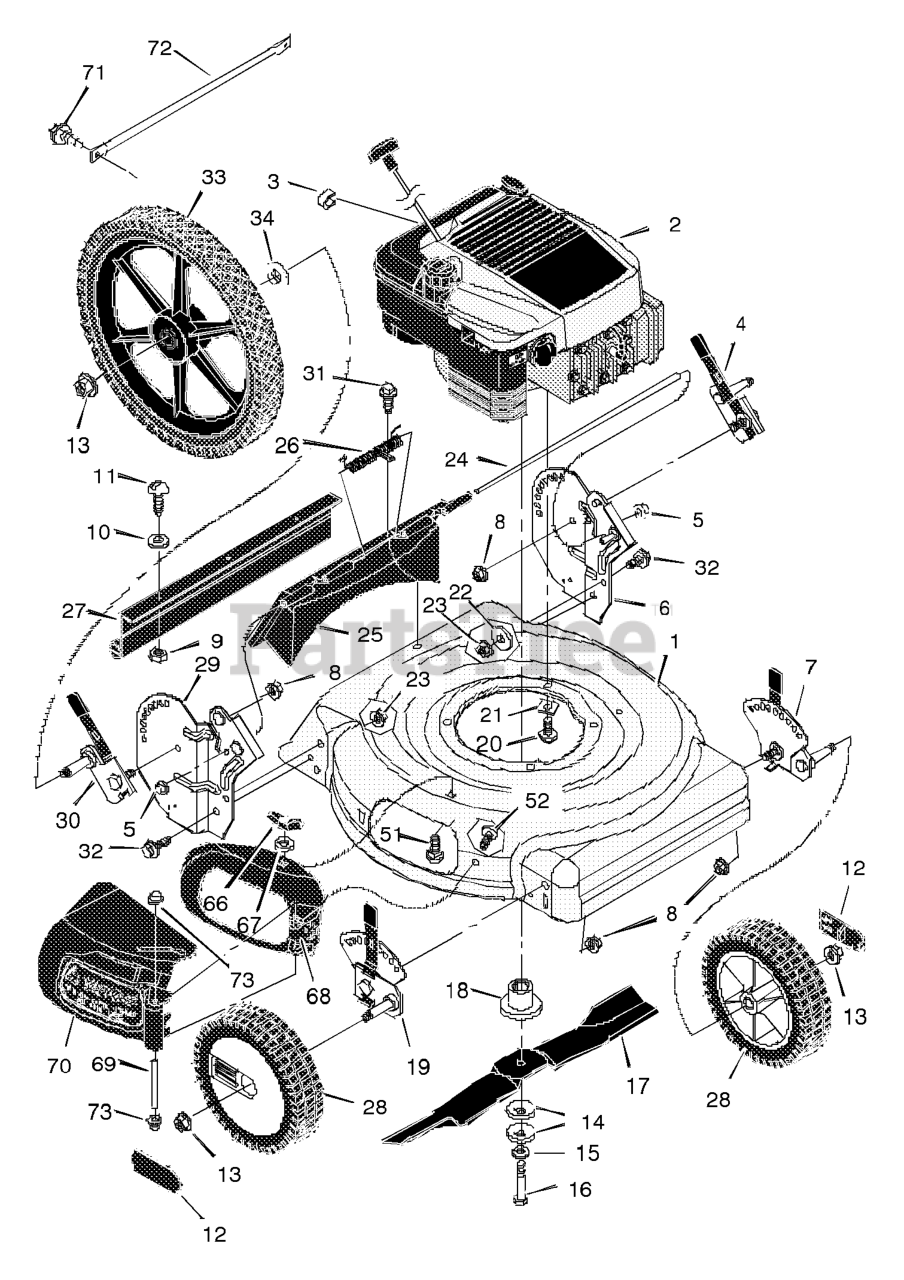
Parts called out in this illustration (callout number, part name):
1	Housing
2	Engine *
3	Stop, Rope (Recoil - Start)
4	Adjuster, Left Height
5	Push On Cap
6	Bracket, Left Handle
7	Adjuster, Left Front Height
8	Nut, Flange
9	Nut, Hex
12	Hub Cap
13	Nut, Flange
14	Washer, Belleville
18	Adapter, Blade
19	Adjuster, Right Front Height
20	Bolt, Engine
21	Support, Engine
22	Washer
23	Nut, Flange
24	Rod, Pivot
25	Door, Rear
27	Guard, Rear
28	Wheel (Light Gray)
29	Bracket, Right Handle
30	Adjuster, Right Height
32	Bolt
33	Wheel, Rear
51	Bolt, Carriage
66	Wingnut
67	Retainer, Push
69	Pin, Pivot
70	Deflector, Chute
73	Push On Cap
